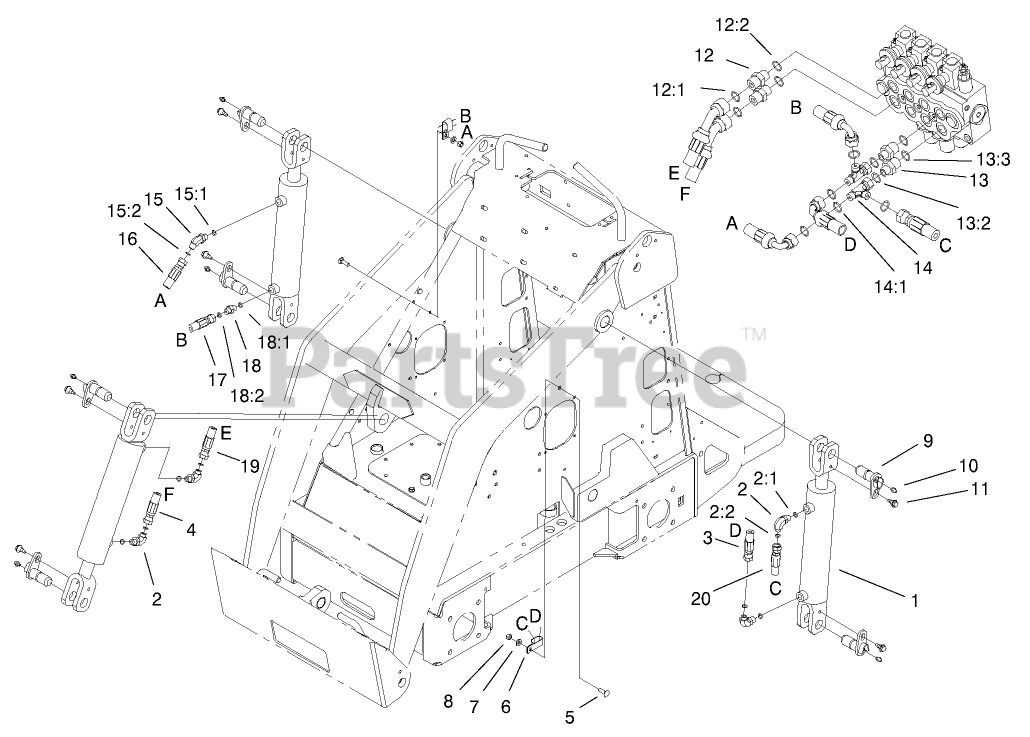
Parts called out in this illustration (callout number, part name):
1	CYLINDER KIT
2	FITTING-ELBOW 90
2:1	O-RING
2:2	O-RING
3	HYD HOSE ASM
4	HOSE-HYD
5	BOLT-CARR
6	CLAMP-R, DOUBLE
7	WASHER-PLAIN
8	NUT-LOCK, NI
9	PIN-PIVOT
10	FITTING-GREASE
11	BOLT-SHOULDER
12	FITTING-STRAIGHT
12:1	O-RING
12:2	O-RING
13	FITTING-STR
13:2	O-RING
13:3	O-RING
14	FITTING-HYD
14:1	O-Ring
15	FITTING
15:1	O-RING
15:2	O-RING
16	HOSE-HYD
17	HOSE-HYD, RIGHT
18	FITTING-STRAIGHT
18:1	O-Ring
18:2	O-RING
19	HOSE-HYD
20	HYD HOSE ASM
